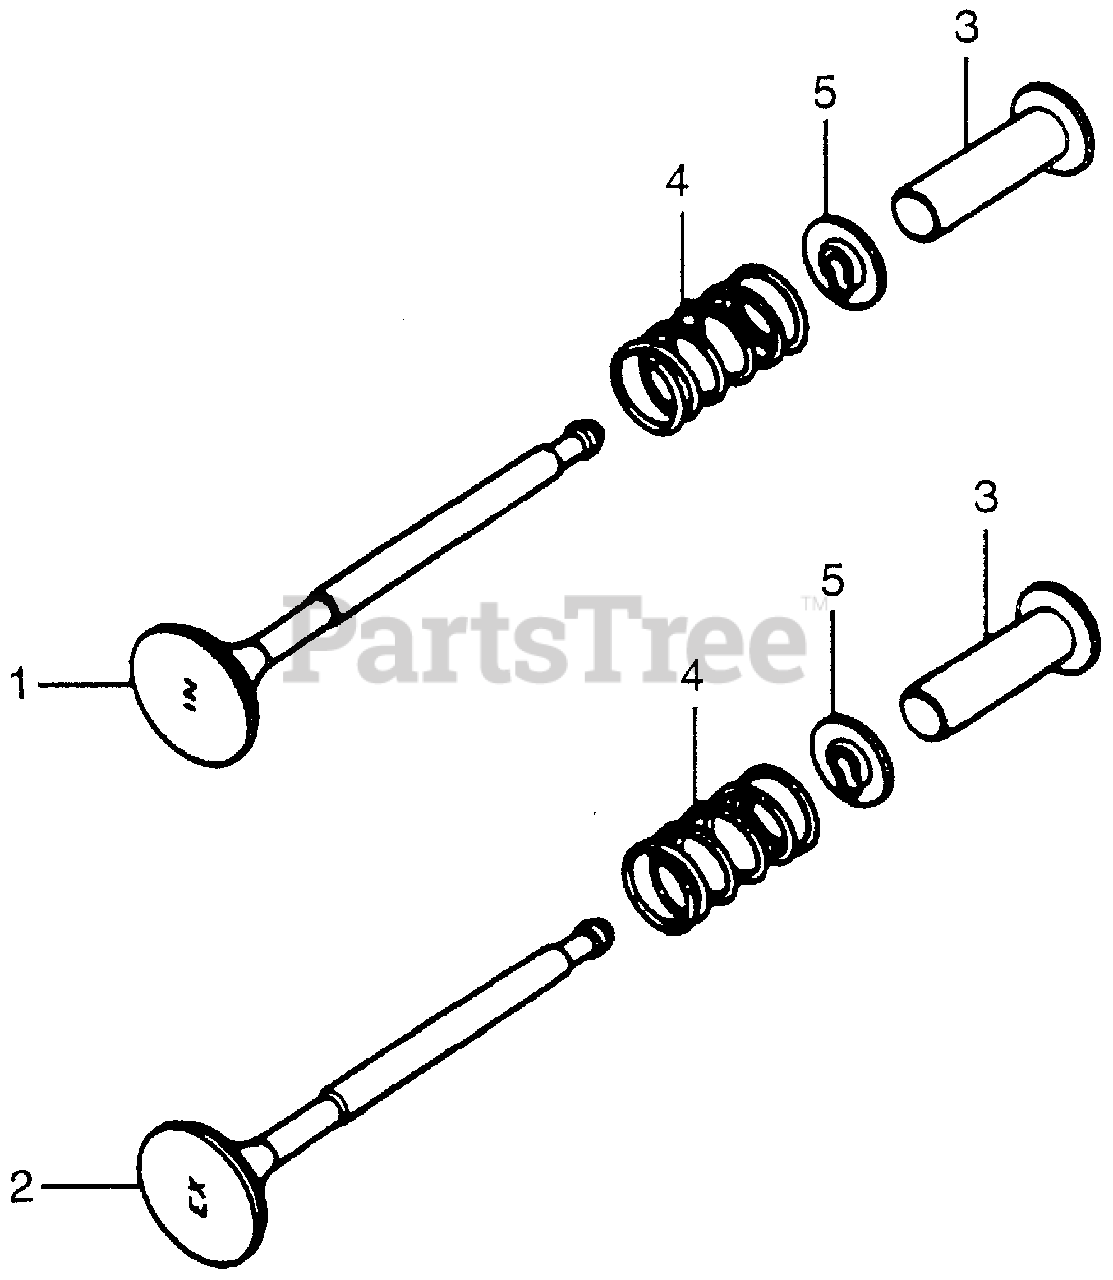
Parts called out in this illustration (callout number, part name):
1	VALVE, IN.
2	VALVE, EX.
3	LIFTER, VALVE
4	SPRING, VALVE (NOT AVAILABLE)
5	RETAINER, VALVE SPRING
